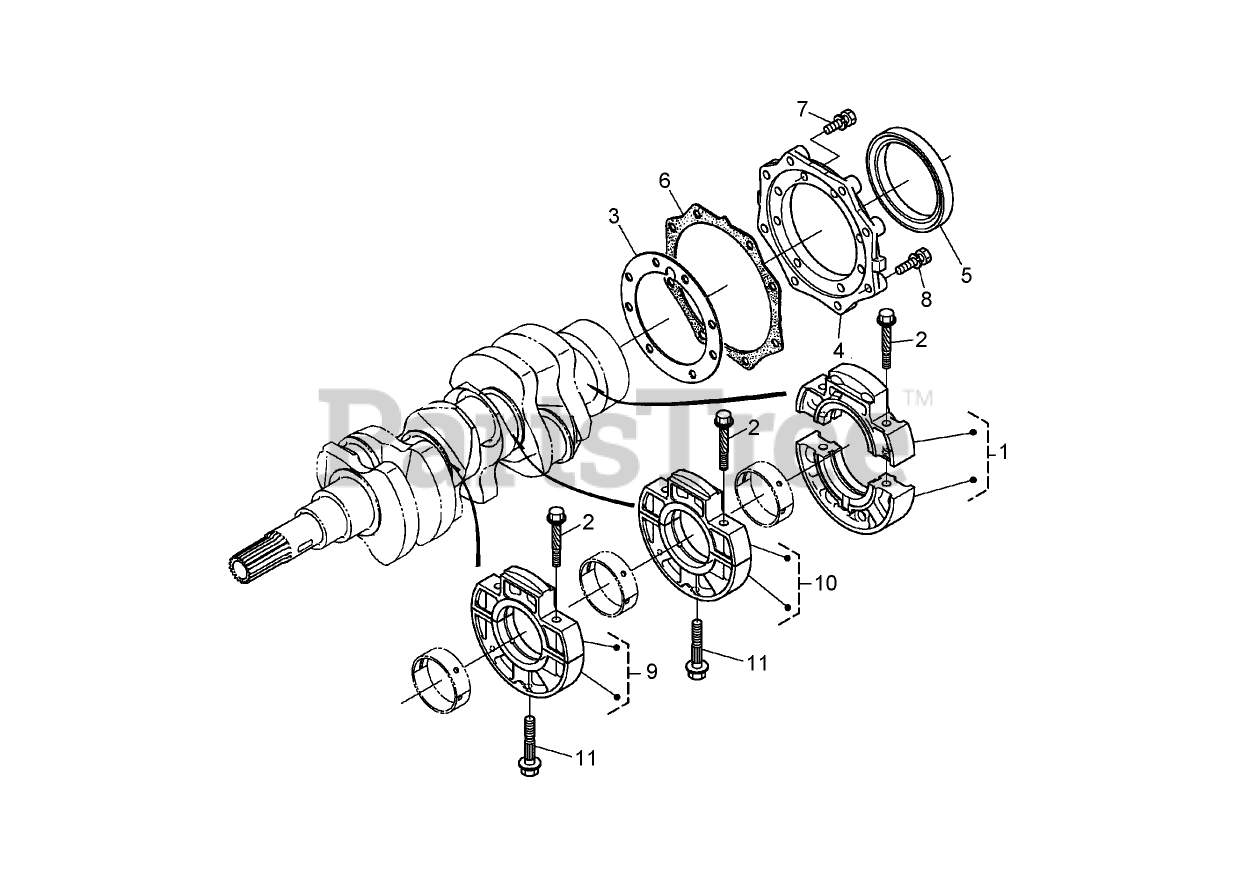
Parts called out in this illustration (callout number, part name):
1	MAIN BEARING CASE ASM
2	BOLT-CASE, BEARING
3	GASKET-CASE, BEARING
4	COVER-CASE, BEARING
5	SEAL-OIL
6	GASKET-COVER, CASE
9	MAIN BEARING CASE ASM
11	BOLT-CASE, BEARING
